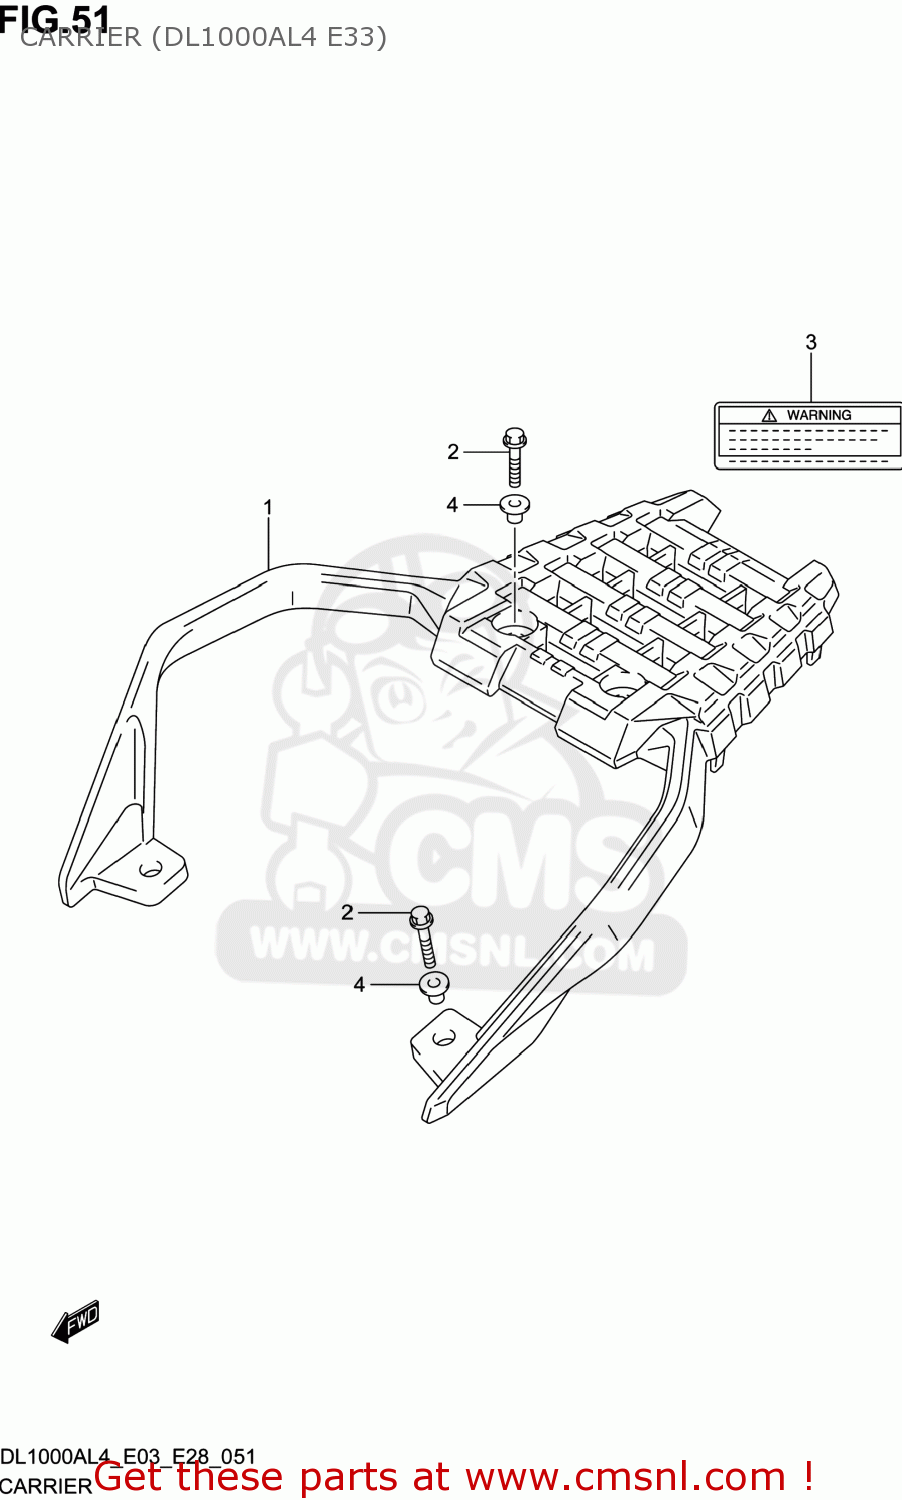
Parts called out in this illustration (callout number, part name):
1	CARRIER,SPORT(SILVER)
2	BOLT(8X35)
3	LABEL,WARNING LUGGAGE CARRIER
4	WASHER
